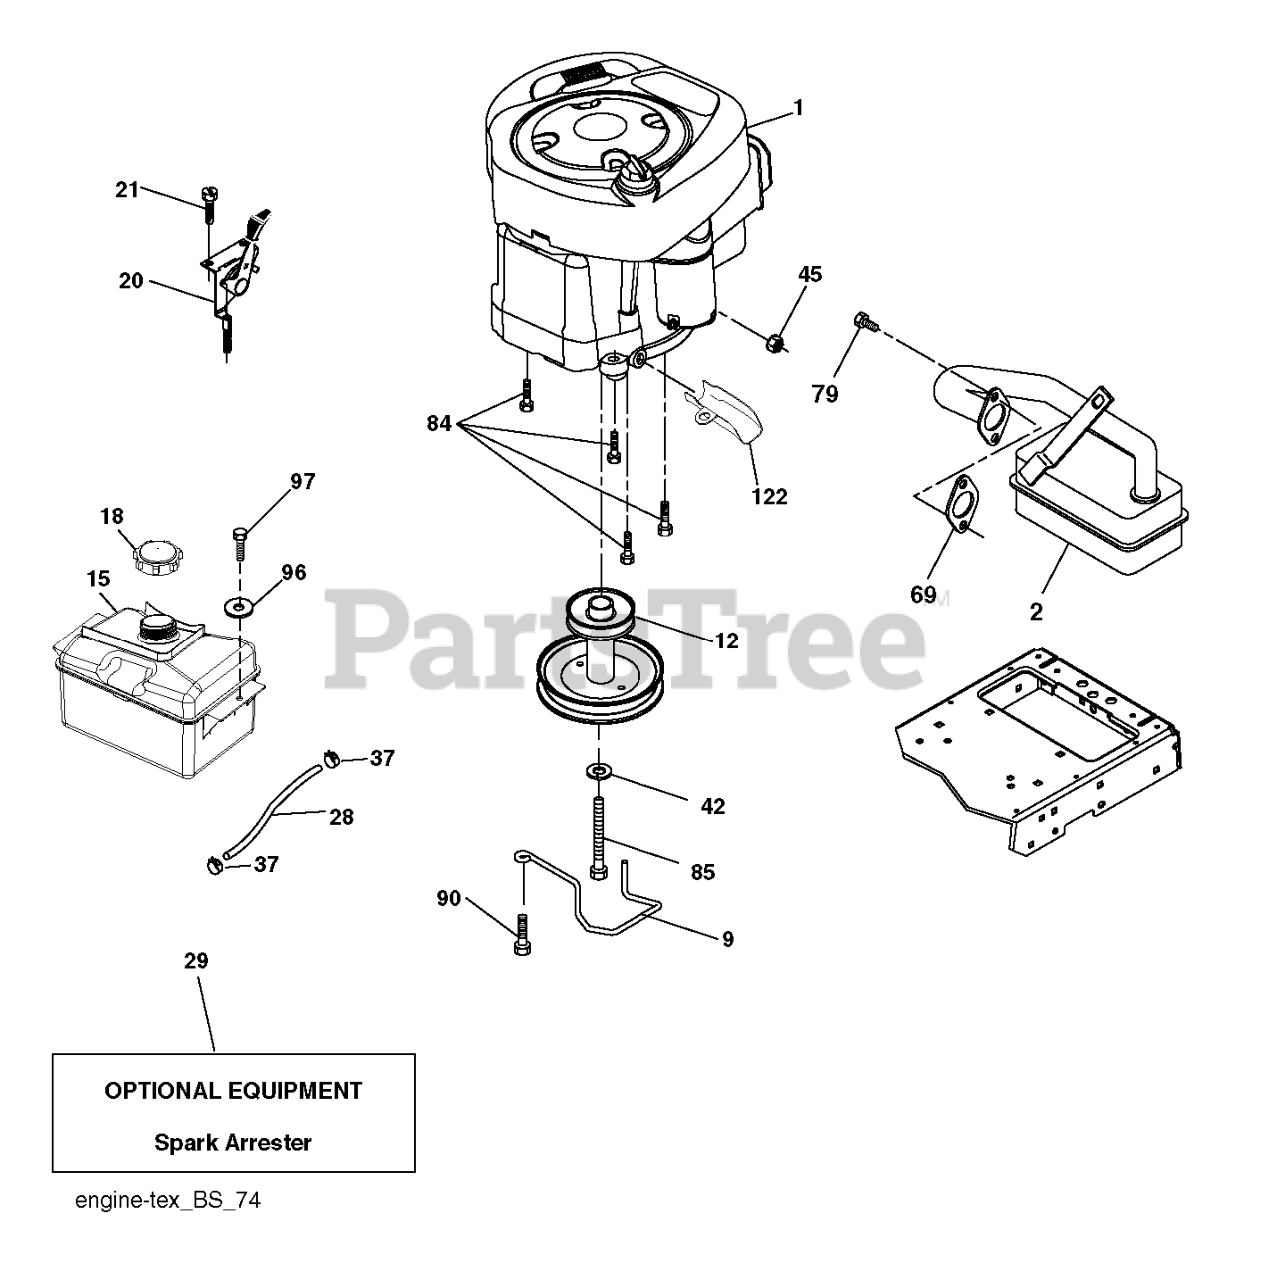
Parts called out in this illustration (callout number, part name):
2	MUFFLER.LT.BRIGGS.14HP.IC/OHV
9	KEEPER.BELT.ENGINE.4.2
12	PULLY ENGINE
15	RP TANK FUEL FRT 1.5 GAL
18	CAP.2.25'.VENTED.TETHER .EPA
20	CONTROL.TH/CK.C.
21	SCREW.#10 X 0.750.BOS
28	LINE.FUEL.20"FRONT.EMI
29	KIT.SPARK ARRESTOR 794945 B&S
37	HOSE CLAMP
42	LOCKWASHER
45	NUT
69	REPL BY 532 27 22-93
79	SCREW.SOCKET HD.5/16-1
84	SCREW.3/8-16
85	BOLT HEX 7/16-20X4-1/4"
90	SCREW 3/8-16X1
97	SCREW HEXWSHR 1/4-20X3/4
122	EXTENSION DRAIN OIL
